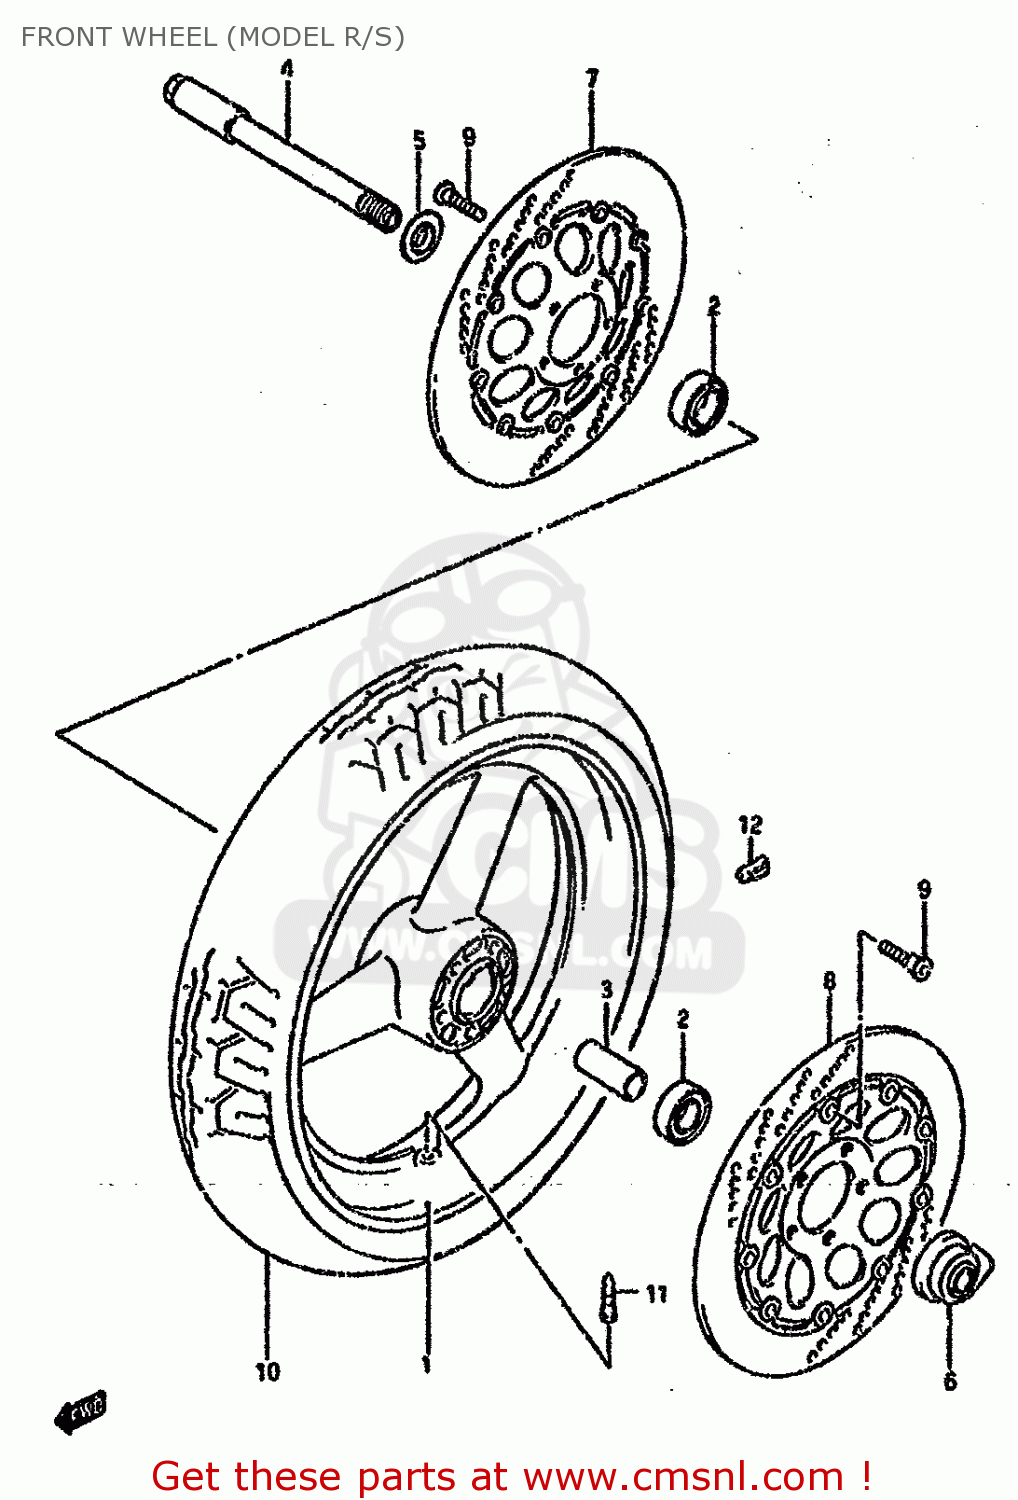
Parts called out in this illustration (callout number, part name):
1	WHEEL,FRONT
2	BEARING
3	SPACER(20.8X27.2X74)
4	AXLE,FR
5	SPACER,FR HUB BEARING,R
6	BOX ASSY,SPEEDOMETER GEAR
7	DISC,FR BRAKE,R
8	DISC,FR BRAKE,L
9	BOLT 8X33
10	TIRE,FRONT 120/70ZR17 D20
11	VALVE ASSEMBLY,WHEEL,TR412
12	BALANCER,WHEEL
